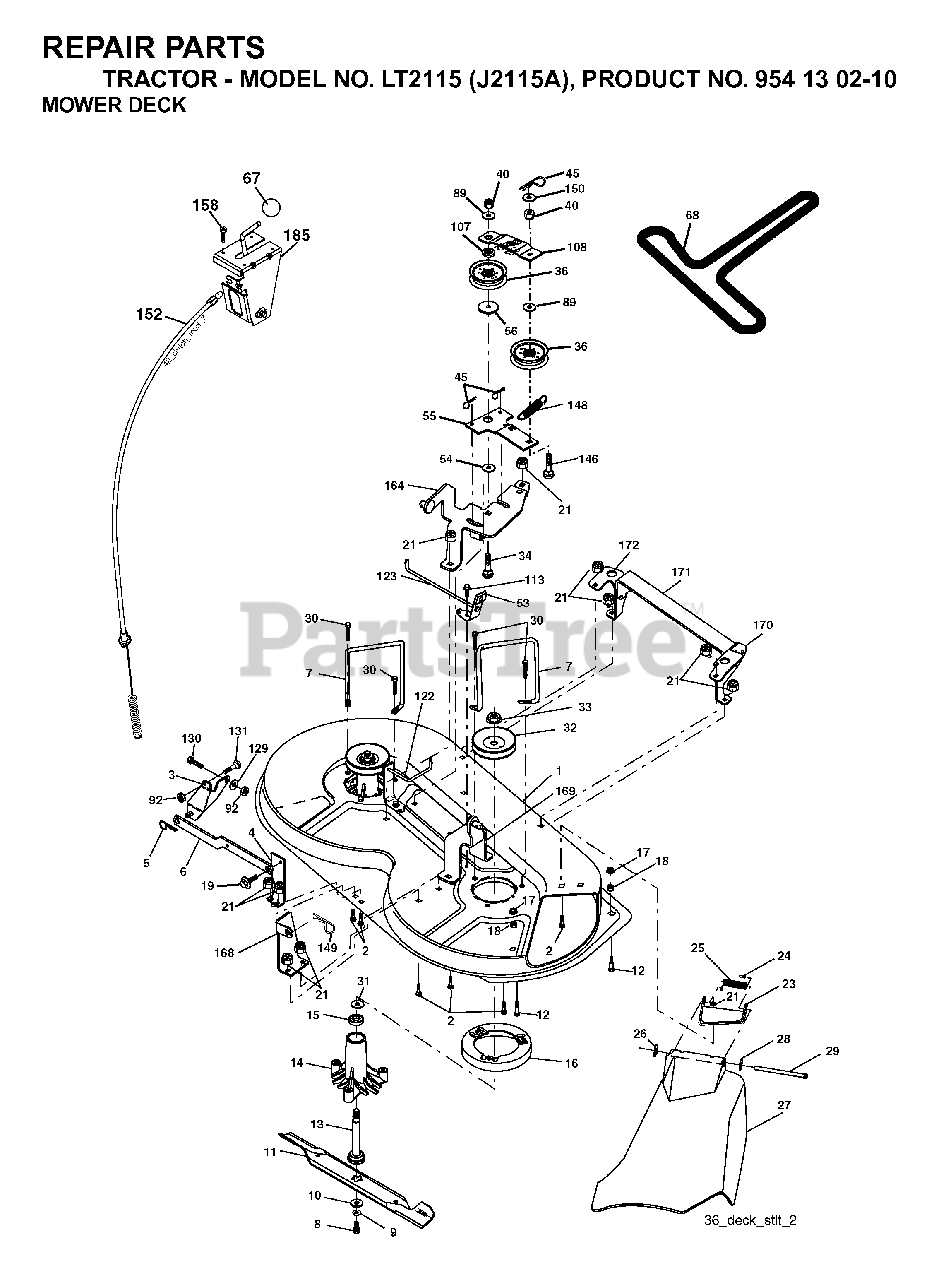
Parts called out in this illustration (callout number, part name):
2	BOLT
3	BRKT ASM SWAY BAR
5	RETAINER-SPRNG RB
6	BAR SWAY DECK
7	KEEPER LH
8	BLADE BOLT
9	LOCKWASHER
10	WASHER.BLADE
11	BLADE, HI-LIFT 36" PREMIUM
13	SHAFT ASM VENT
14	HSG MANDREL
16	STRIPPER, MWR ROUND
19	BOLT SHD 5/16-18
21	LOCKNUT
23	BRACKET ASM DEFLECTOR
24	CAP-SLEEVE LT
25	SPRING TORSION
26	NUT PUSH M
28	WASHER
29	HINGE ROD
30	SCREW, WASHER HEAD
31	WASHER.SPACER.MANDREL
32	PULLEY, MANDREL
33	NUT, FLG TOPLOCK 9/16"
34	BOLT
36	FLAT IDLER PULLEY
40	LOCKNUT
45	RETAINER M
53	BRAKE ASSEMBLY
55	IDLER ARM
56	SPACER.RETAINER.MOWER
67	KNOB T (3/8 HOLE)
68	V-BELT.MOWER.
89	WASHER
92	NUT
107	SPACER.IDLER.ARM
108	STIFFENER.IDLER.ARM
129	WASHER
131	BOLT D
146	BOLT, CARRIAGE IDLER
148	IDLER RETURN SPRING
149	SPRING.RETAINER.YELLOW.ZINC
150	WASHER PM
158	SCREW
171	BRACE
185	HEAD ASM. CABLE CLUTCH
